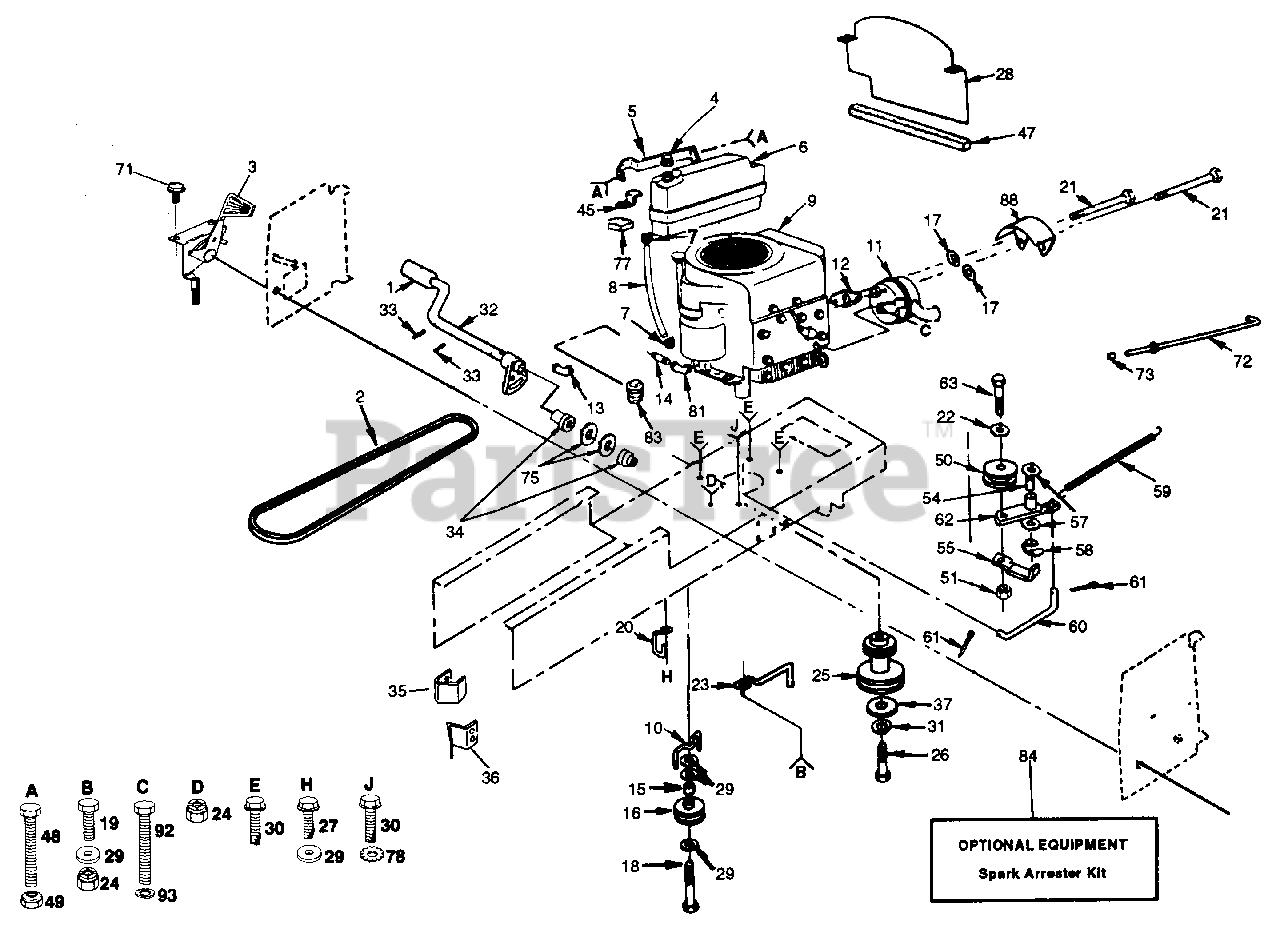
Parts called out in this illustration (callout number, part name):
1	Cover, Pedal (AYP part number)
2	V-Belt, Drive (AYP part number)
3	Control, Throttle (AYP part number)
4	Cap, Fuel (AYP part number)
5	Support, Tank, Fuel (AYP part number)
6	Tank, Fuel (AYP part number)
7	Clamp, Hose (AYP part number)
8	Line, Fuel (AYP part number)
10	Belt, Keeper (AYP part number)
11	Muffler (AYP part number)
12	Gasket, Exhaust (AYP part number)
13	90ø Street Elbow 3/8 NPT (AYP part number)
14	Std. Pipe Nipple 3/8-18 NPT x 3-1/2 (AYP part number)
15	Spacer (AYP part number)
16	Idler, Flat (AYP part number)
17	Washer 15/32 x 1 x 16 Gauge (AYP part number)
18	Bolt, Hex 3/8-16 x 2-3/4 (AYP part number)
19	Bolt, Hex 3/8-16 x 1 (AYP part number)
20	Retainer, Belt, Chassis, L.H. (AYP part number)
21	Bolt, Shoulder 5/16-18 (AYP part number)
22	Washer 13/32 x 13/16 x 16 Gauge (AYP part number)
23	Keeper, Belt, Engine (AYP part number)
24	Nut, Crownlock 3/8-16
25	Pulley, Engine (AYP part number)
26	Bolt, Hey 7/16-20 x 4-1/4 Grade 5 (AYP part number)
27	Screw, Hex Washer Thread Rolling 3/8-16 x 3/4 (AYP part number)
28	Baffle, Verticle (AYP part number)
29	Washer 13/32 x 13/16 x 12 Gauge (AYP part number)
30	Screw, Hex, Washer Head, Thread Rolling 3/8-16 x 1 x 1/4, Type TT (AYP part number)
31	Washer, Lock (AYP part number)
32	Shaft, Pedal Foot (AYP part number)
33	Pin, Roll 3/16 x 1 (AYP part number)
34	Bearing, Nylon (AYP part number)
35	Keeper, Belt, L.H. (AYP part number)
36	Keeper, Belt, R.H. (AYP part number)
37	Washer (AYP part number)
45	Brace, Tank (AYP part number)
47	Strip, Foam (AYP part number)
48	Bolt, Hex 5/16-18 x 3/4 Grade 5 (AYP part number)
49	Locknut 5/16-18 Grade 8
50	Pulley, Idler
51	Locknut 3/8-16
54	Bearing (AYP part number)
55	Retainer, Belt (AYP part number)
57	Washer, Hardened (AYP part number)
58	Ring, Klip (AYP part number)
59	Spring, Return, Clutch (AYP part number)
60	Link, Clutch (AYP part number)
61	Pin, Cotter 1/8 x 3/4 (AYP part number)
62	Bellcrank Assembly (Inc. Key No. 54) (AYP part number)
63	Bolt, Hex 3/8-16 x 1-1/2 (AYP part number)
71	Screw, Hex Thread Cutting 1/4-20 x 5/8 (AYP part number)
72	Rod, Brake, Park (AYP part number)
73	Cap, Plunger (AYP part number)
75	Washer 21/32 x 1 x 16 Gauge (AYP part number)
77	Pad, Spacer (AYP part number)
78	Washer, Lock, External Tooth 3/8 (AYP part number)
81	45ø Street Elbow (AYP part number)
84	Kit, Arrester, Spark (AYP part number)
88	Shield, Heat, Muffler (AYP part number)
92	Bolt, Hex 1/4-20 x 1/2 Grade 5 (AYP part number)
93	Washer, Lock 1/4 (AYP part number)
